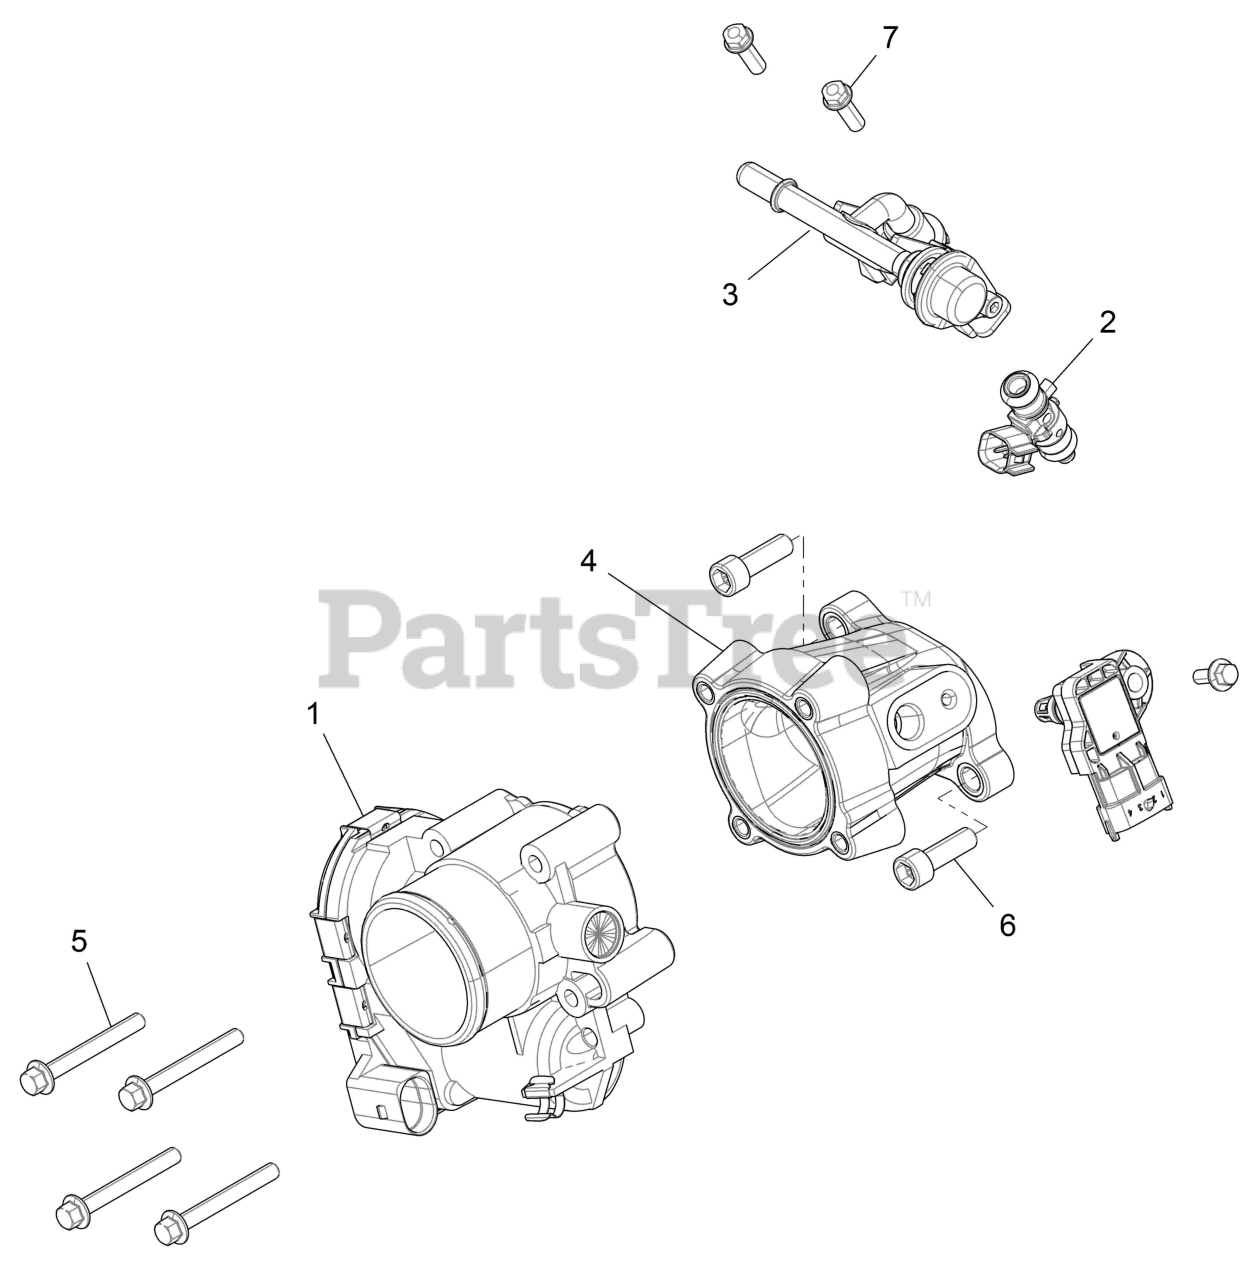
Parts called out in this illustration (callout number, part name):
1	THROTTLE-ETC,46MM
2	INJ-FUEL,EV14COMPACT,200G
2	O-RING-BOSH,EV-14,UPPER
2	O-RING, GREEN, LOWER
3	RAIL-FUEL,1CYL(4-BAR_SCHDRLESS
4	ADAPTER, THROTTLE BODY, ETC
5	SCR-M6X1.0X50.0 HX/FL-YD (10)
6	SCR-M6X20,HXFLG,0600214
7	SCR-SH-M8X1.25X25 8.8 ZPC
